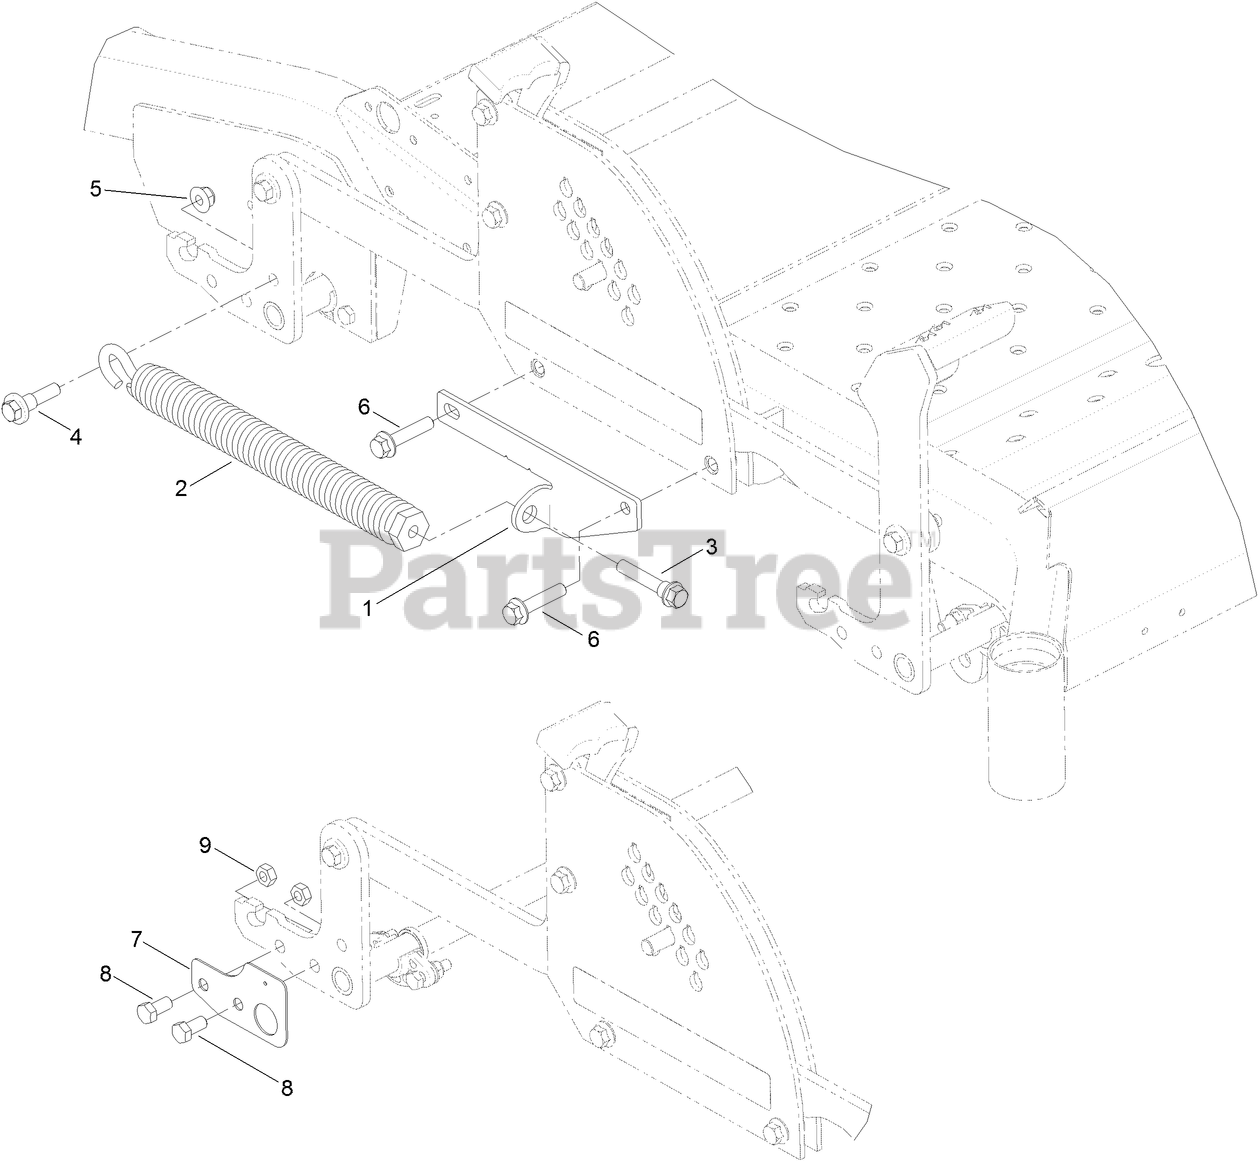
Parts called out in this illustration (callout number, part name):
1	SUPPORT-SPRING
2	SPRING-EXTENSION
3	BOLT-SHOULDER
4	BOLT-SHOULDER
5	NUT-HF, NI
6	SCREW-HHF
7	TEMPLATE
8	SCREW-HH
9	NUT-HEX
